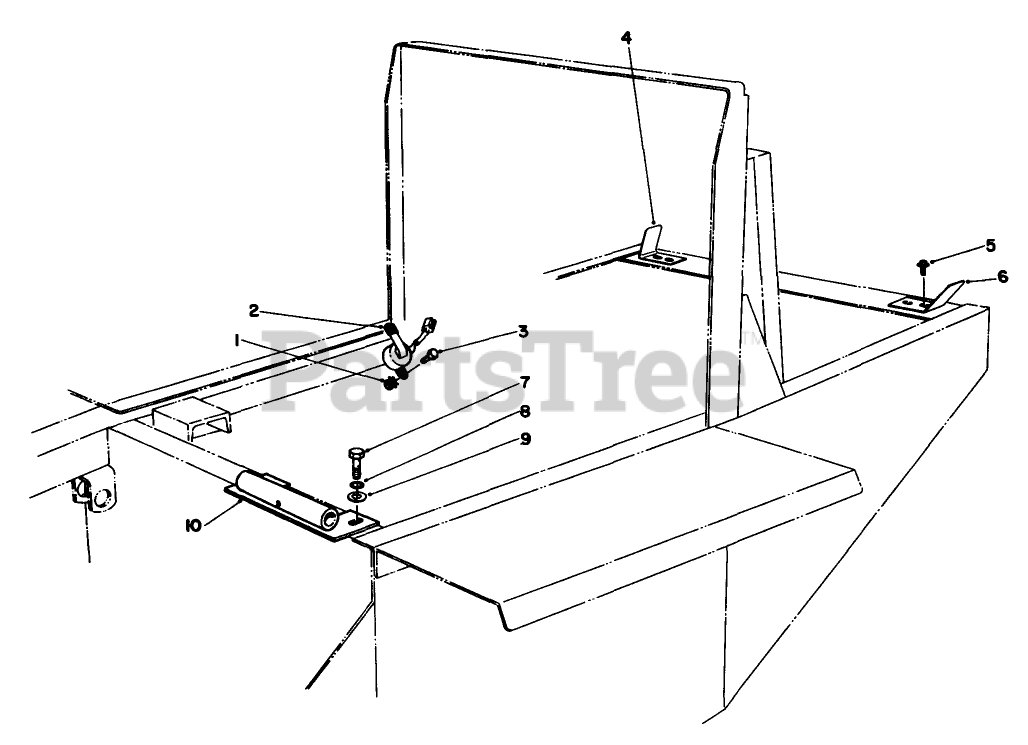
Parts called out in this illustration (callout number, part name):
1	NUT-LOCK, NI
2	SWITCH ARM
3	SCREW-HH
4	Bracket-RH
5	SCREW-HHFTF
6	Bracket-LH
7	SCREW-HHF
8	WASHER-LOCK
9	WASHER-PLAIN
10	Pivot-Seat
